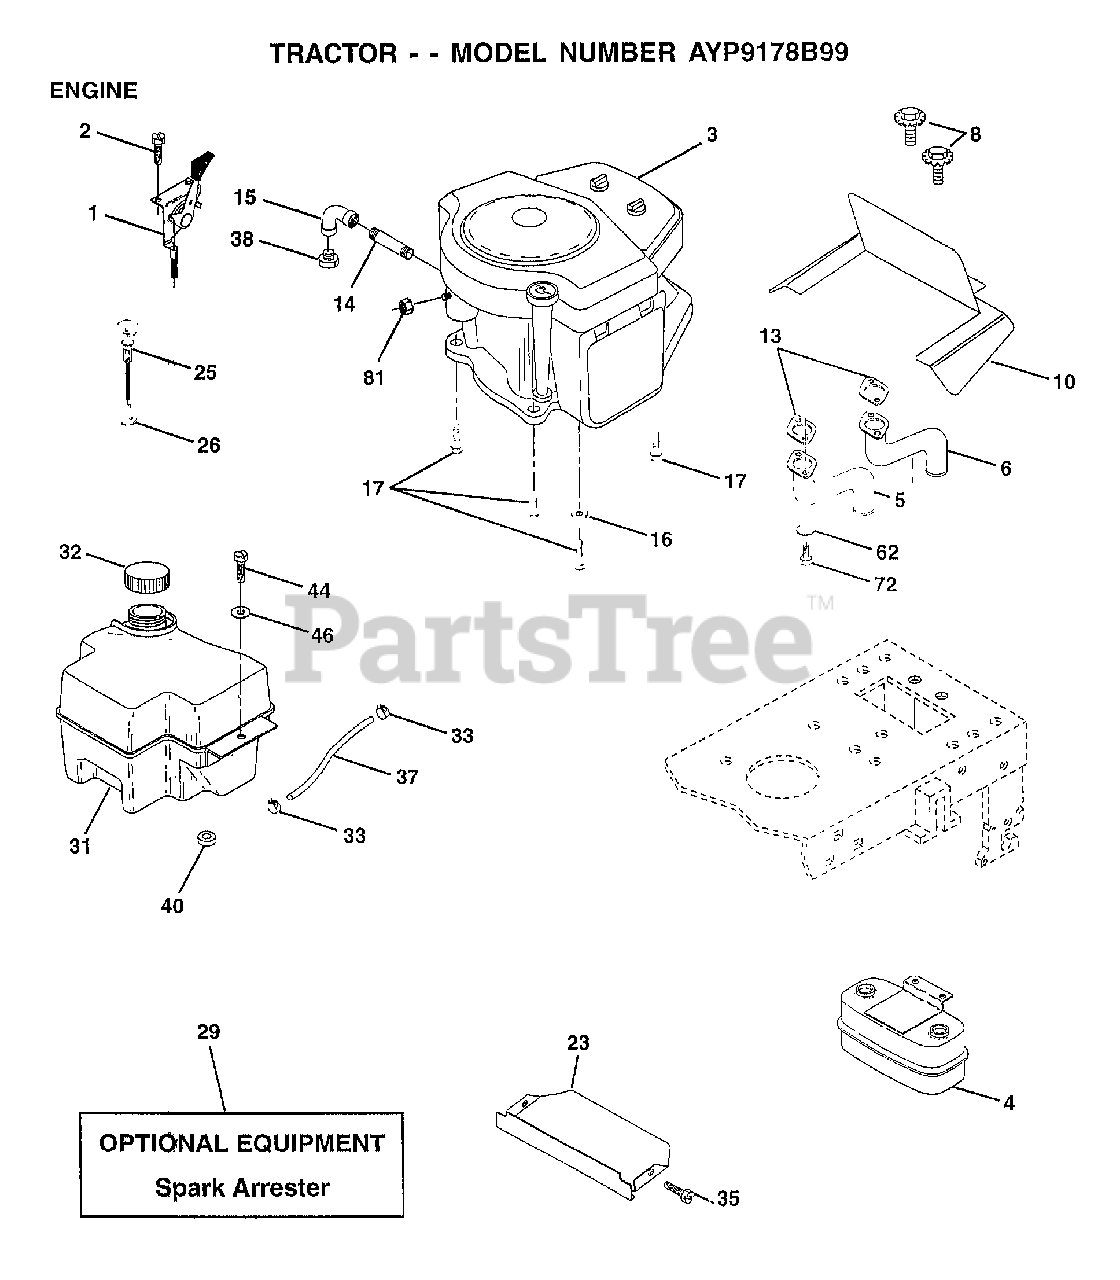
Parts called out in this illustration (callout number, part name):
1	CONTROL THROT. LH
2	SCREW LT
4	MUFFLER.TW.LOTONE
5	TUBE MANIFOLD LH
6	TUBE MANIFOLD RH
8	BOLT.5/16-18.UNC
10	SHIELD.BROWNING
14	PIPE NIPPLE LT
15	ELBOW
16	LOCKWASHER
17	SCREW LT
23	SHIELD.BRN/DBR.GD
25	CONTROL.CHOKE.37
26	"NUT,KEPS 3/8-24IM"
31	TANK.FUEL.FRONT.
32	CAP ASM FUEL
33	HOSE CLAMP
35	SCREW
37	LINE FUEL
44	SCREW HEX CRT
46	WASHER
62	LOCKWASHER
72	SCREW
81	NUT
